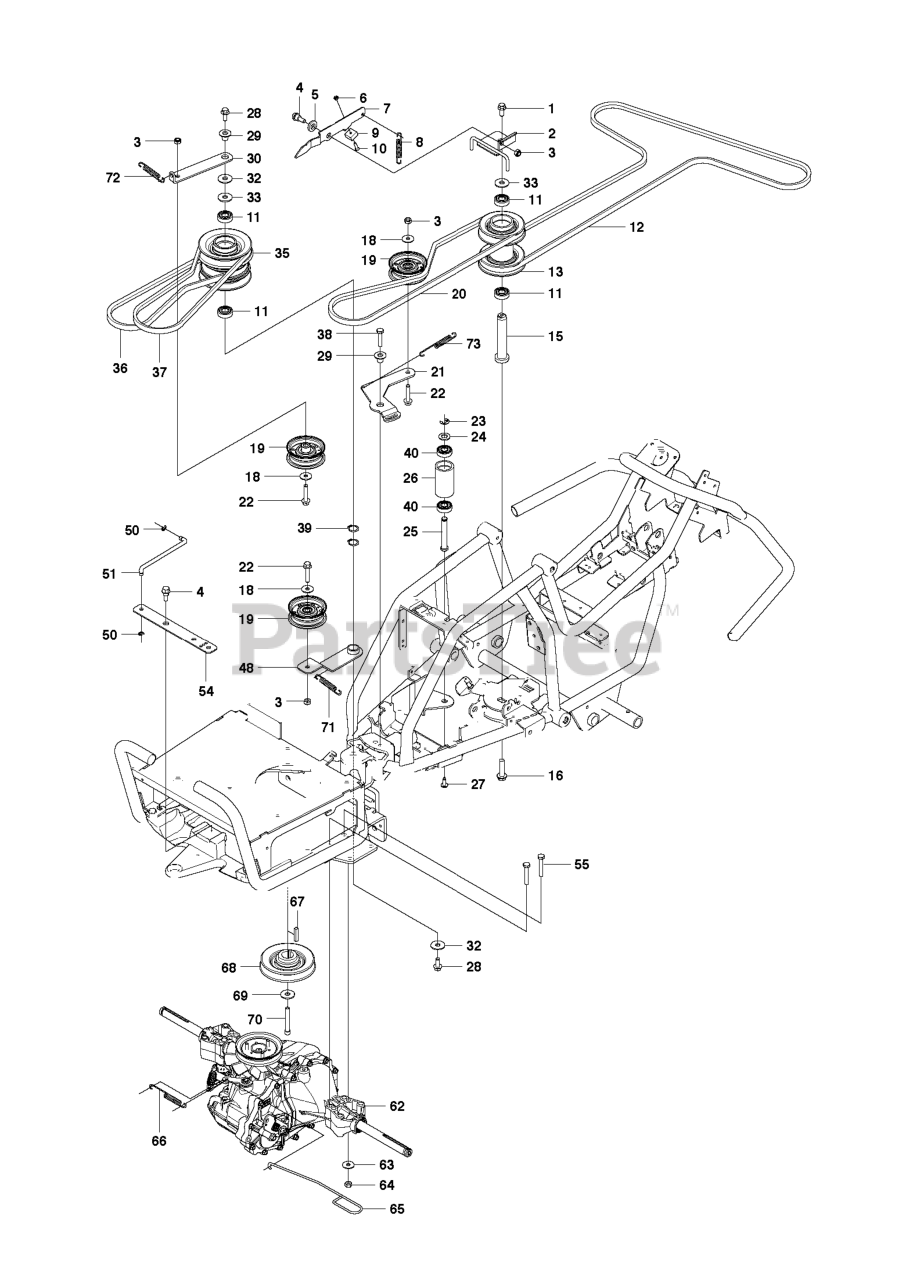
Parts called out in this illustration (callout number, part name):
3	LOCKNUT M8
6	LOCKNUT M5
11	BALL BEARING 6004-2RS1
19	IDLER PULLEY
21	BELT TENSIONER
23	RETAINING RING
24	WASHER - M12
28	BOLT
29	WASHER
38	BOLT
39	RETAINING RING SGA 20
40	BALL BEARING 6201-2RS1
63	WASHER BRB 8.4X17
64	NUT
